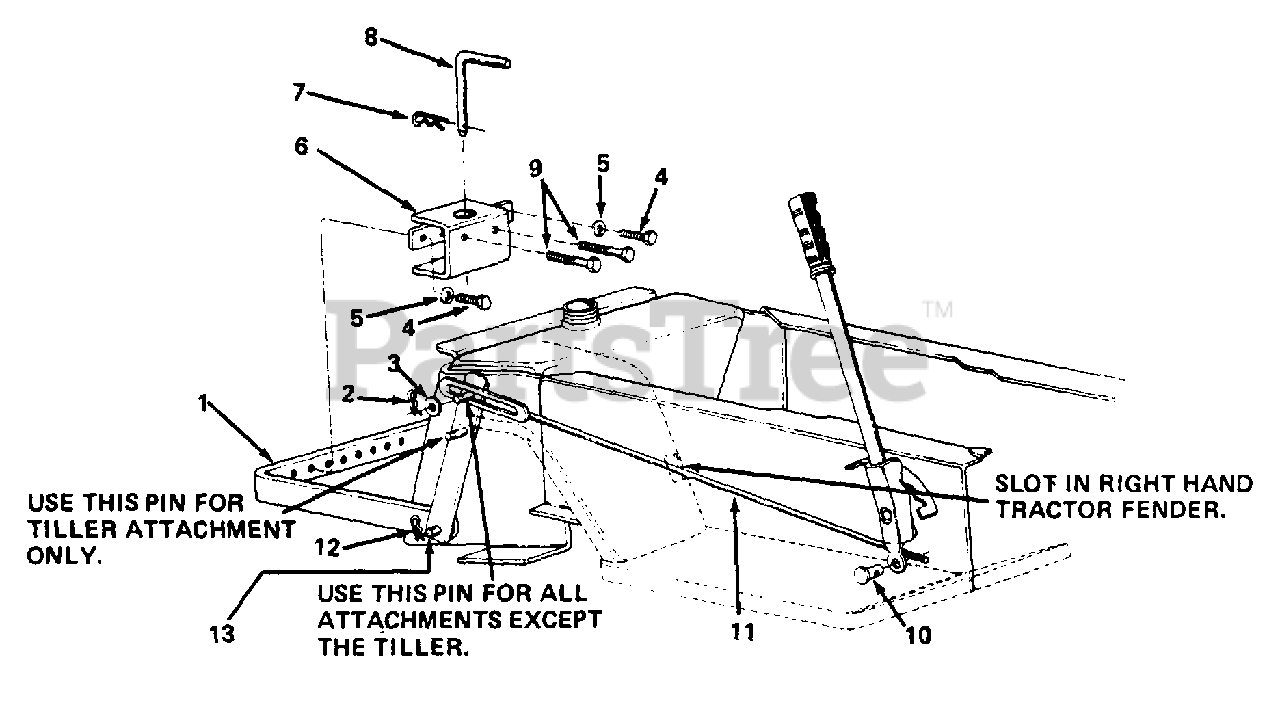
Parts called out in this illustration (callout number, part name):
3	Fl.-Wash. 1/2" I.D.
4	Hex Scr. 1/2-13 x 1.00" Lg.
5	L-Wash. 1/2" Scr.
6	Hitch Brkt. Ass'y.
7	Internal Cotter Pin 5/8" Dia
8	Hitch Pin
9	Hex Scr. 1/2-13 x 3.00" Lg.
10	Adjustment Ferrulle
13	Hitch Rod
